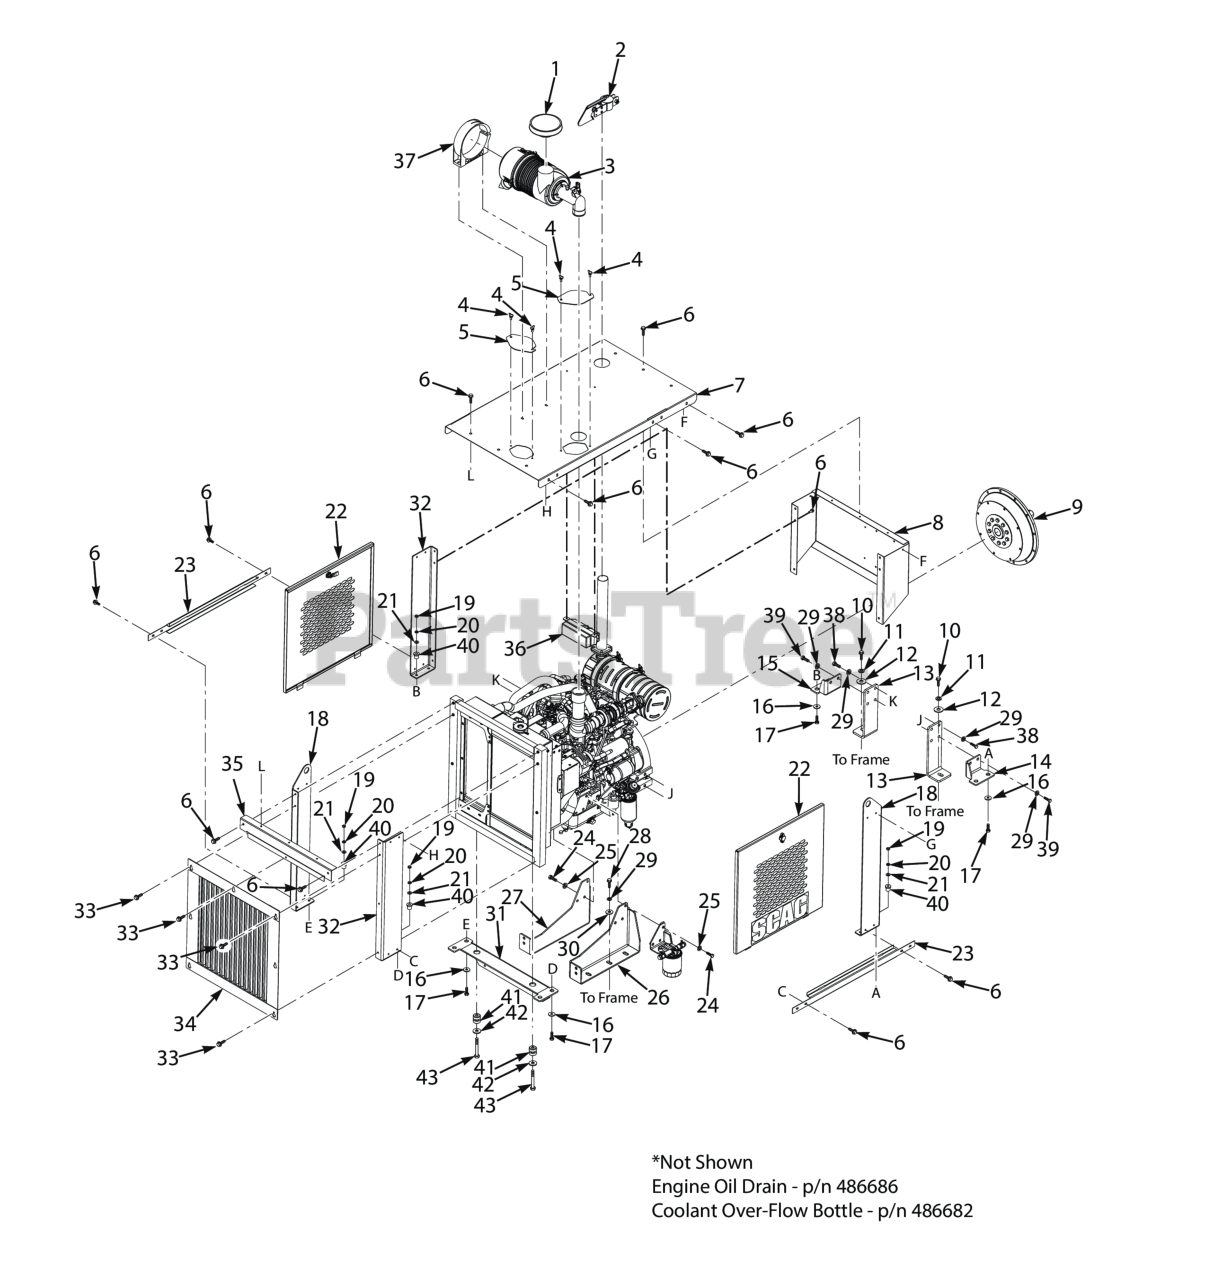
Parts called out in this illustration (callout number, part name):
1	Rain Cap, Air Cleaner
2	Rain Cap Assy, Exhaust
3	Air Cleaner Assy.
4	Screw, Thumb, 5/16-18 x .625
5	Enclosure, Cover
6	Capscrew, 5/16-18 x .75 Serrated Flange Hex Head
7	Top, Enclosure
8	Front, Enclosure
9	Stub Shaft Assy.
10	Bolt, Hex Head, 5/8-11 x 1-3/4"
11	Lockwasher, 5/8" Spring
12	Flatwasher, 5/8-.688 x 1-3/4 x .134 HD
13	Engine Mount, Rear
14	Support, Enclosure, LH Rear
15	Support, Enclosure, RH Rear
16	FW, .375-.406 X 1.25 X .125
17	Bolt, Hex Head 3/8-16 x 1-3/4" (Kohler EFI)
18	Lifting Rail, Enclosure
19	HEX LOCKNUT, ELASTIC STOP, 3/8-16
20	Lockwasher, 3/8" Spring, Kawasaki FX / FS
21	Flatwasher, 3/8 (.406 x .812 x .065)
22	Side Panel, Enclosure
23	Enclosure, Bottom Rail
24	HHCS, M12-1.125 X 30 LG
25	LKWASH, M12 METRIC SPRING
26	Engine Mount, LH Front
27	Engine Mount, RH Front
28	Bolt, Hex Head 1/2-13 x 1-3/4"
29	Lockwasher, 1/2" Spring
30	Washer, Flat, 1/2-.562 x 1.375 x .109 HD
31	Support Weldment, Radiator Lower
32	Side Rail, Enclosure
33	CAP SCREW, 5/16-18 X 1/2" SERRATED FLANGE HEX
34	Debris Screen Weldment
35	Enclosure Support, Rear
36	Controller
37	Band, Air Cleaner
38	Bolt, Hex Head 1/2-13 x 1-1/4"
39	Bolt, Hex Head 1/2-13 x 1-1/2", (STT-52 & STTII-52)
40	Isolator Mount
41	Isolator Mount, Sleeved
42	FW, .50-.531 X 2.0 X .125
43	Bolt, Hex Head 1/2-13 x 2-3/4" (48V & 52V - One Weight)
